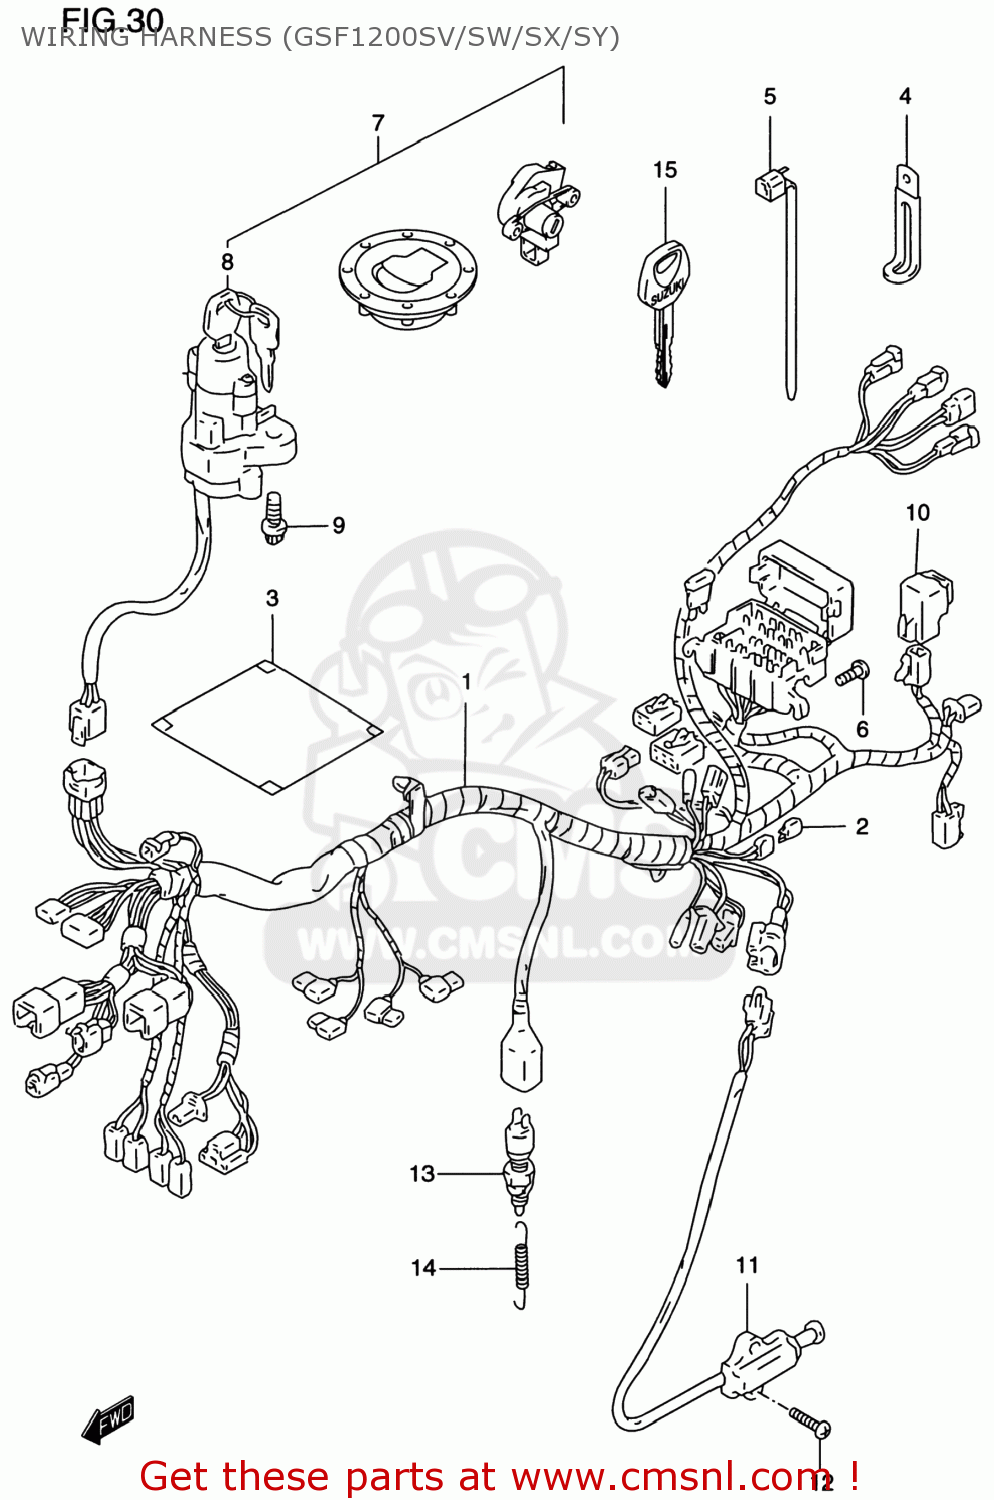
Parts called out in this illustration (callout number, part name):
1	HARNESS,WIRING
2	DIODE(STANLEY DE8804)
3	COVER,WIRING HARNESS
4	CLAMP L:62
5	CLAMP(L:95)
6	SCREW 6X12
7	LOCK SET
8	LOCK ASSY,STEERING
9	BOLT(8X20)
10	RELAY ASSY
11	SWITCH ASSY,SIDE STAND
12	SCREW
13	SWITCH ASSY,STOP LAMP
14	SPRING
15	KEY,BLANK
